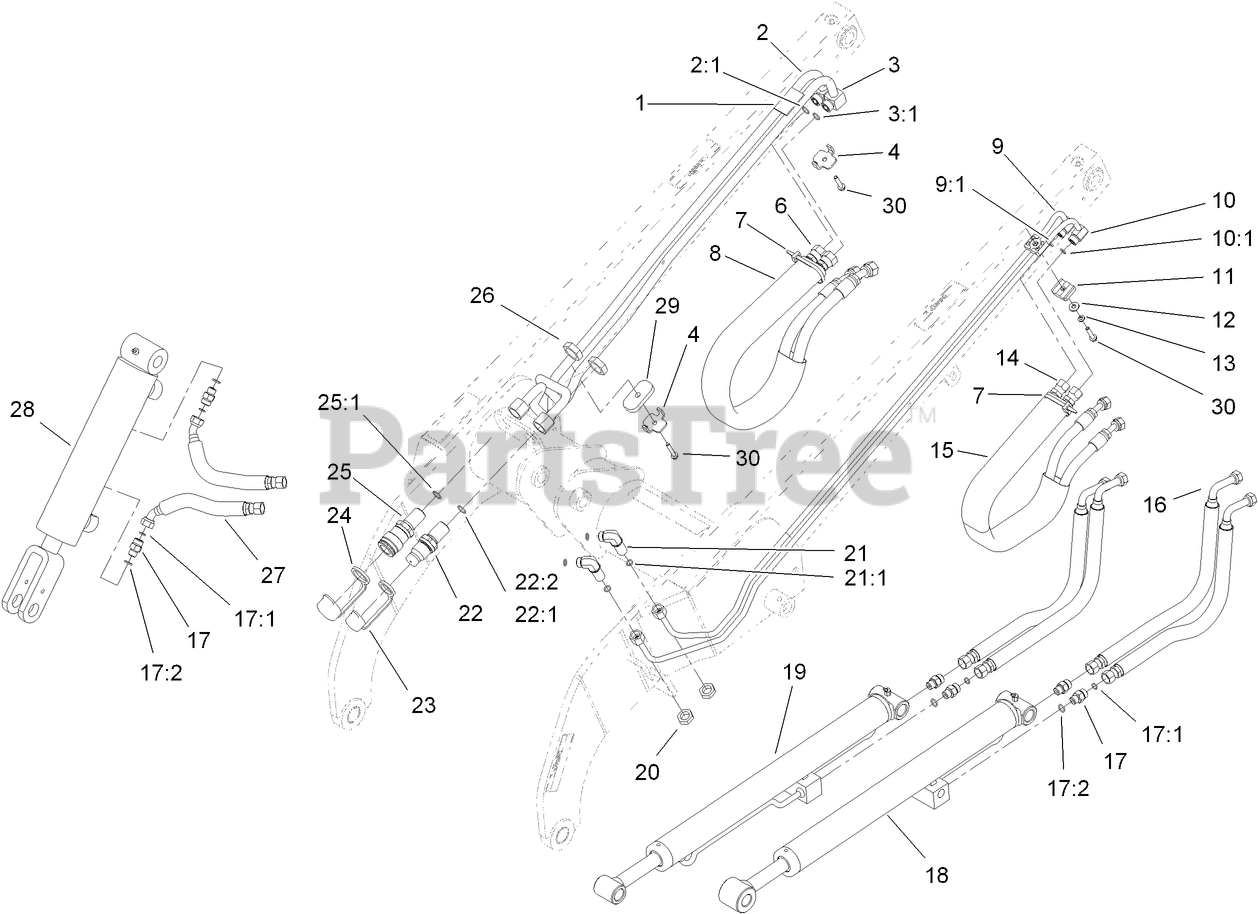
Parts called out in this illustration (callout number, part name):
1	SPACER-HARDLINE
2	HYD TUBE ASM
2:1	O-RING
3	HYD TUBE ASM
3:1	O-RING
4	PLATE-CLAMP, TUBE
6	HOSE-HYD
7	TIE-CABLE
8	SLEEVE-PROTECTIVE
9	HYD TUBE ASM
9:1	O-RING
10	HYD TUBE ASM
10:1	O-RING
11	CLAMP-TUBE
12	WASHER-FLAT
13	WASHER-LOCK
14	HOSE-HYD
15	SLEEVE-PROTECTIVE
16	HOSE-HYD
17	FITTING-STRAIGHT
17:1	O-RING
17:2	O-RING
18	LH LIFT CYLINDER ASM
19	RH LIFT CYLINDER ASM
20	NUT-LOCK
21	UNION-BULKHEAD
21:1	O-RING
22	BULKHEAD NIPPLE ASM
22:1	O-RING
23	CAP-DUST, NIPPLE
24	CAP-DUST, COUPLER
25	BULKHEAD COUPLER ASM
25:1	O-RING
26	NUT-LOCK, BULKHEAD
27	HOSE-HYD
28	TILT CYLINDER ASM
29	PLATE-HARDLINE
30	SCREW-HWH
